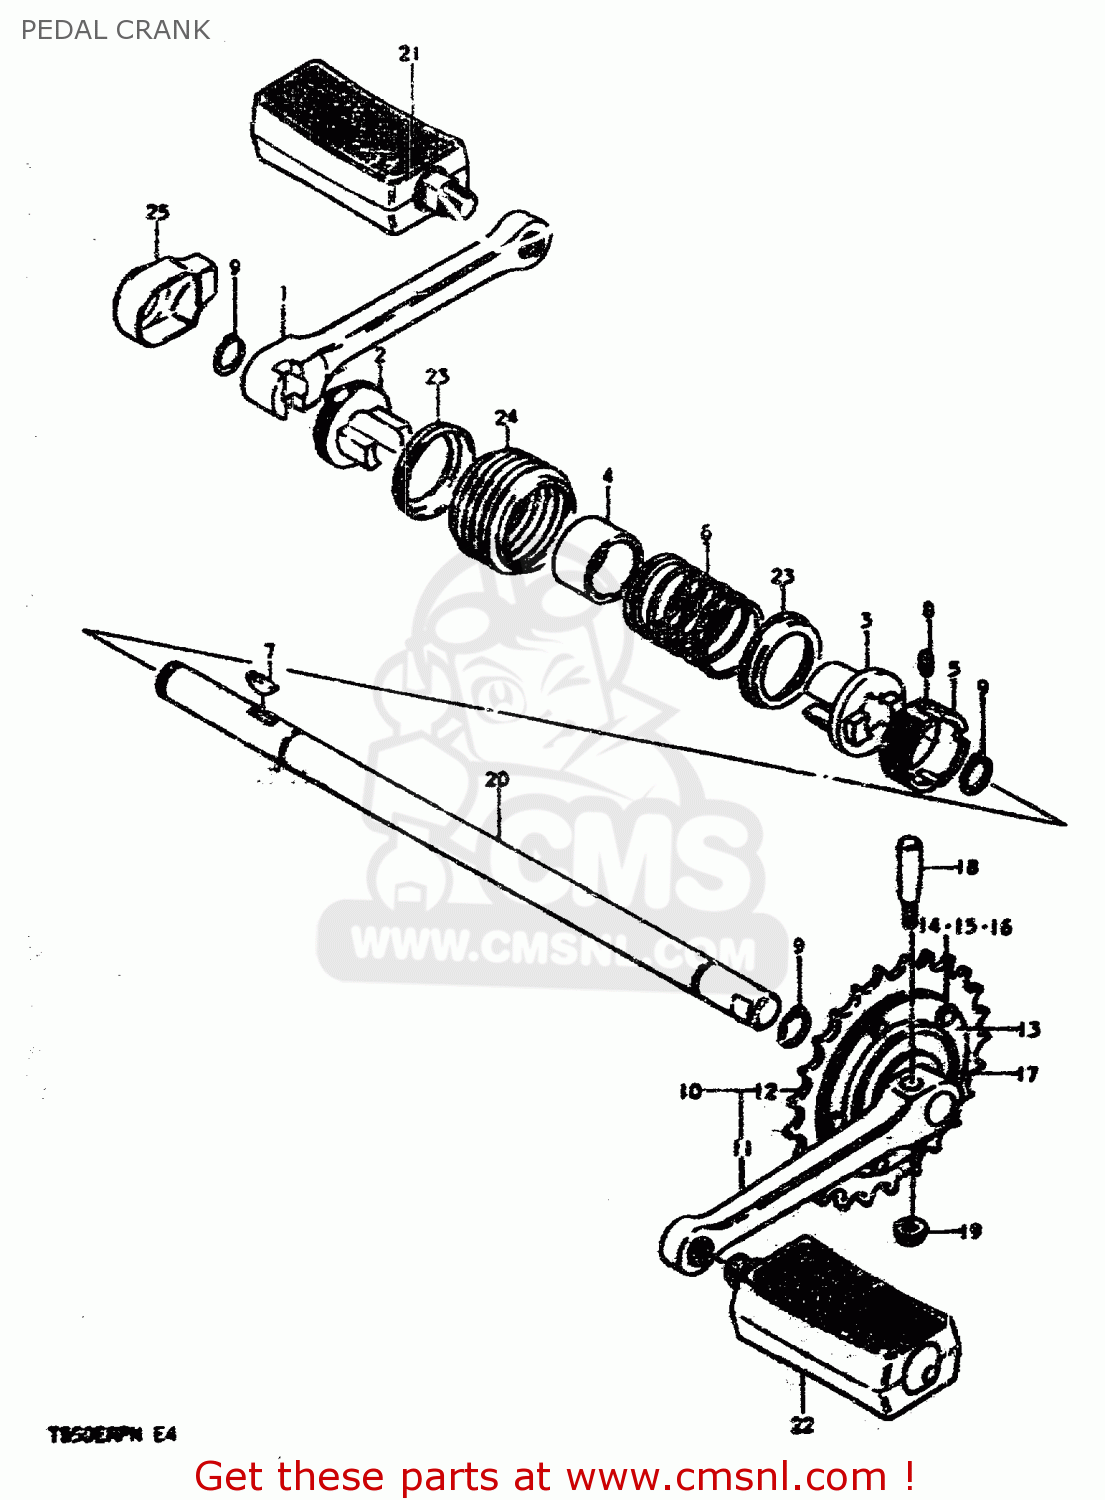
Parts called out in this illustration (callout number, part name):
1	CRANK, RH
2	DOG, OUTER
3	DOG, INNER
4	SLEEVE, CRANK
5	STOPPER, DOG
6	SPRING
7	KEY
8	SPRING PIN
9	CIRCLIP,16MM
10	GEAR CRANK ASSY
11	CRANK, LH
12	SPROCKET
13	SPACER
14	NUT 6MM
15	LOCK WASHER
16	BOLT(6X14)
17	FREE WHEEL
18	PIN
19	NUT
20	SHAFT, CRANK
21	PEDAL ASSY, RH
22	PEDAL ASSY, LH
23	COLLOR, DUST SEAL CRANK
24	DUST SEAL, CRANK
25	CAP, CRANK
